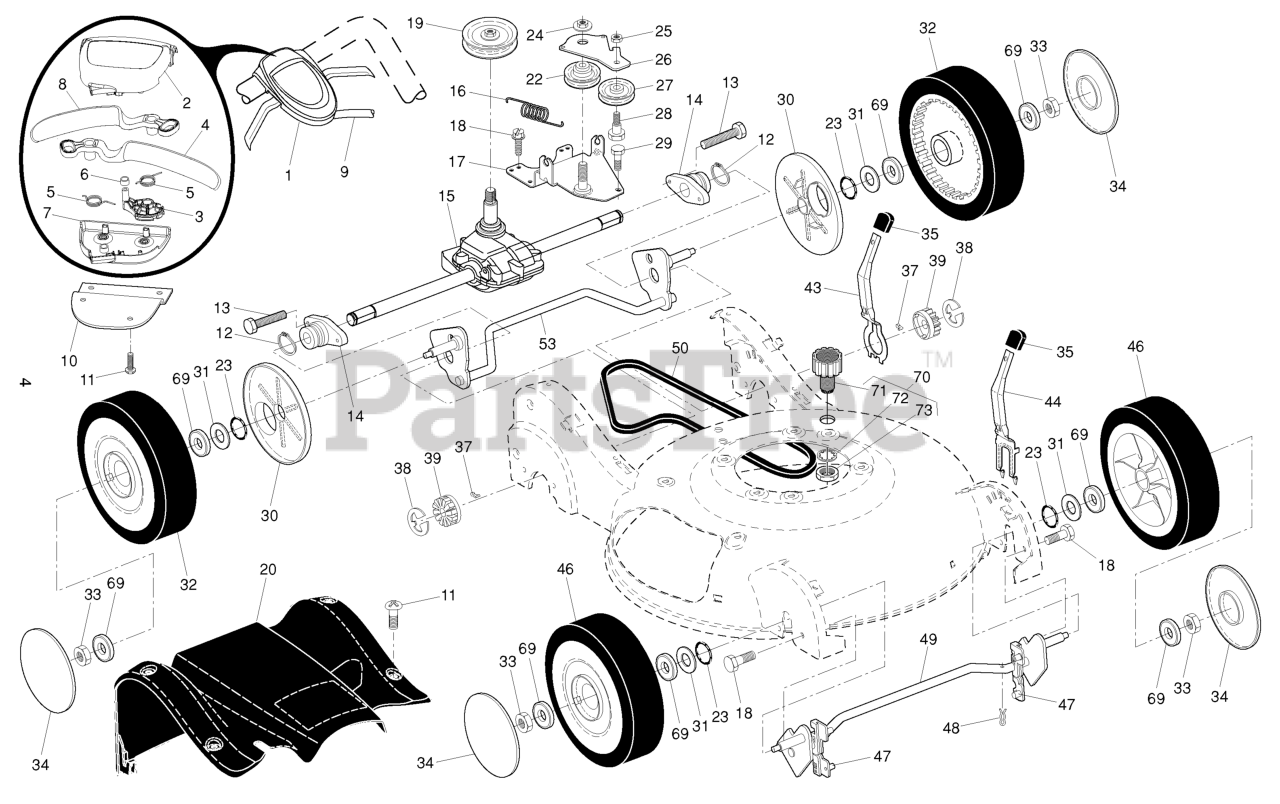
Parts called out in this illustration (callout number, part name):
1	Drive Control Assembly
2	RP CASE.CONT.ROL.TOP.HUSQV.
3	CAM.GEN2.DUAL.TRIGGER
4	LEVER.CONTROL.RH.22+.CURV.BLAC
5	SPRING, DRIVE CONTROL
6	BUSHING.CONTROL.CAM
7	COVER.DR.CONTROL.LOWER.GRAY
8	LEVER.CONTROL.LH.22+.CURVE.BLA
9	CABLE.CONTROL.HIVAC.GEN2
10	BRACKET.DRIVE.CONTR.GEN2.BLACK
11	SCREW, PHILLIPS HEAD 10 X 5/8
12	RETAINING RING (2 2)(3 2)
13	HINGE SCREW
14	BEARING / AXLE SUPPORT
15	TRANSMISSION.21.HV.RWGD.AW/EZ
17	BRACKET, GEAR CASE / DRIVE
19	RP PULLEY.DRIVE.EZ
20	COVER.DR.ASM.408006X418.CE
22	PULLEY.IDLER.V-BELT
23	O-RING..070X.487.NEOPRENE
24	NUT.HEX.FLANGE.3/8-16.LOCKNUT
25	NUT.CENTERLOCK.5/16-
26	ARM.IDLER.BZP
27	IDLER PULLEY
28	SHOULDER BOLT
29	SCREW 14-20 X 5/8
30	DUST COVER, WHEEL
31	WASHER.FLAT.1/2
32	WHEEL.9X2.25.LP.TIGER.BLACK
33	NUT.HEX.FLANGE.3/8-16.LO(3 2)
34	HUBCAP.WHEEL.5.SPOKE.SILVER
35	KNOB.SELECTOR.SPRING.BLACK(3 2
37	PAWL, DRIVE
38	E-RING 7/16 RE
39	PINION.14.TEETH.FGD
43	LEVER, SELECTOR, HEIGHT, REAR
44	LEVER, SELECTOR, HEIGHT, FRONT
46	WHEEL.9X2.25.LP.TIGER.BLK
47	BUSHING.FRONT.TORQUE.SHAFT
48	SPRING RETAINER
49	SHAFT FRONT
50	BELT, DRIVE
53	SHAFT.ASM.REAR.TORQUE.HV.BZP
69	BEARING.8".WHEEL
70	KIT.WASH-OUT.PORT
71	FITTING, HOSE, WATER WASHOUT
72	WASHER.LOCK.INTERNAL.TOOTH
73	LOCKNUT.HEX.WITH.O-RING
